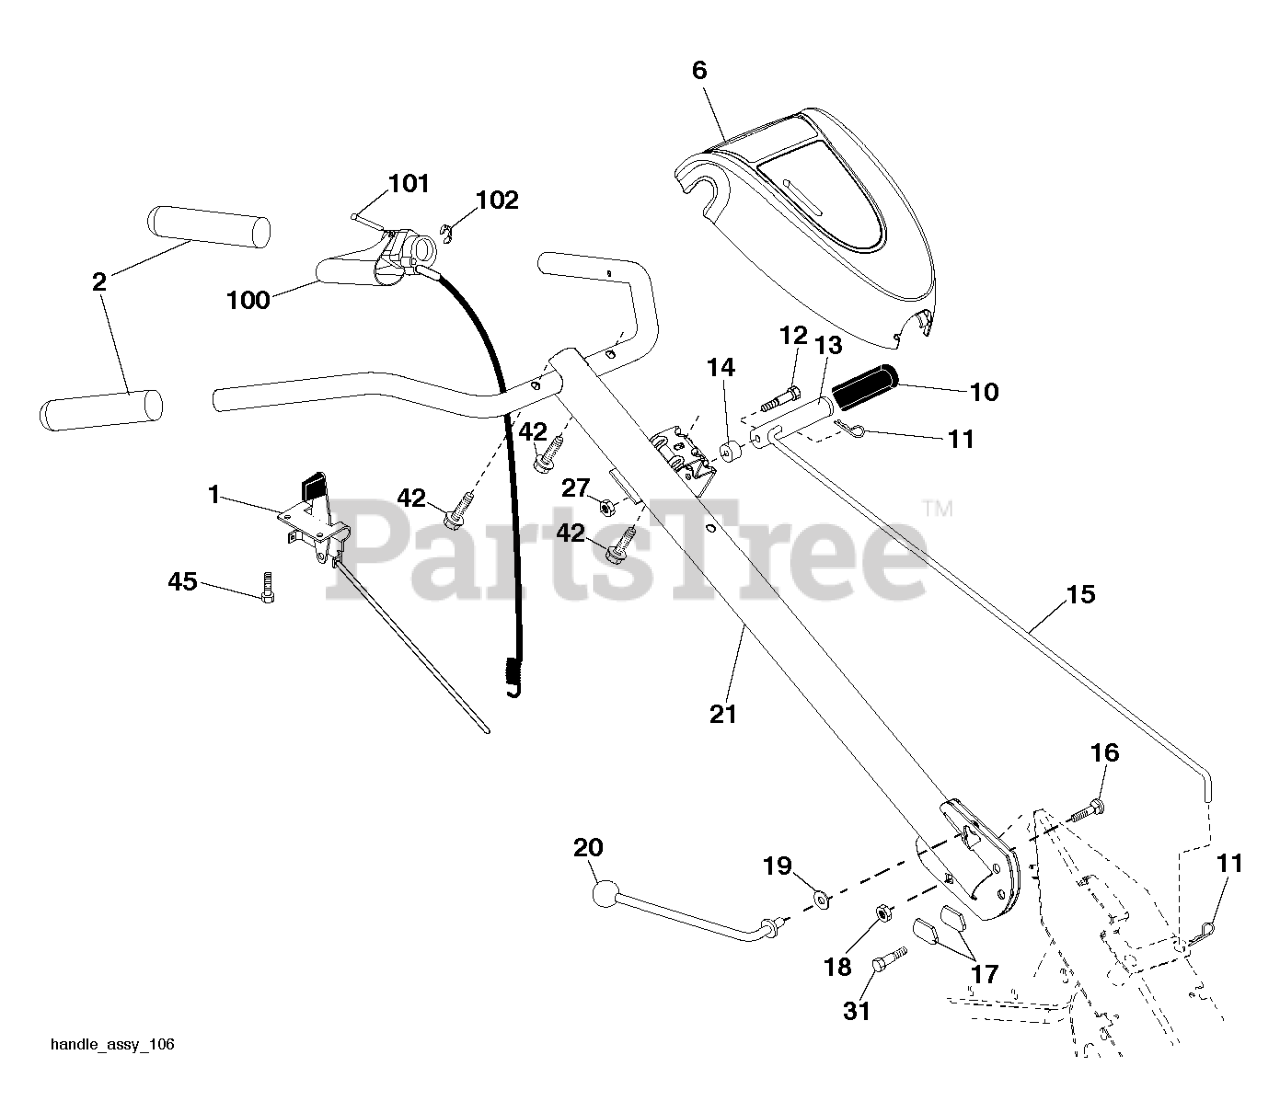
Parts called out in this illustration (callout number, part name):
1	THROTTLE.CONTROL.RT.INTEK.50
2	GRIP.1X5.06
6	CONSOLE.GREY.DRT.W.S.DRT900E
10	GRIP T
11	RETAINER M
12	SHOULDER BOLT ST
13	HANDLE
14	GROMMET.RUBBER.CRT.TILLER
15	ROD.SHIFT.YARD PRO.UNIVERSAL.
16	BOLT D
17	LOCK.HANDLE.CRT
19	WASHER CRT
20	LEVER.LOCK.CRT
21	HANDLE.ASM.HUSQ/P.PRO.GREY
27	NUT T
31	BOLT.PIVOT
42	SCREW.#10 X 0.750.BOS
45	SCREW.#10 X 0.500
100	CONTROL.ASSEMBLY.TINE.TILLER
101	PIN, PIVOT
102	RETAINING.RING.#5103-25
